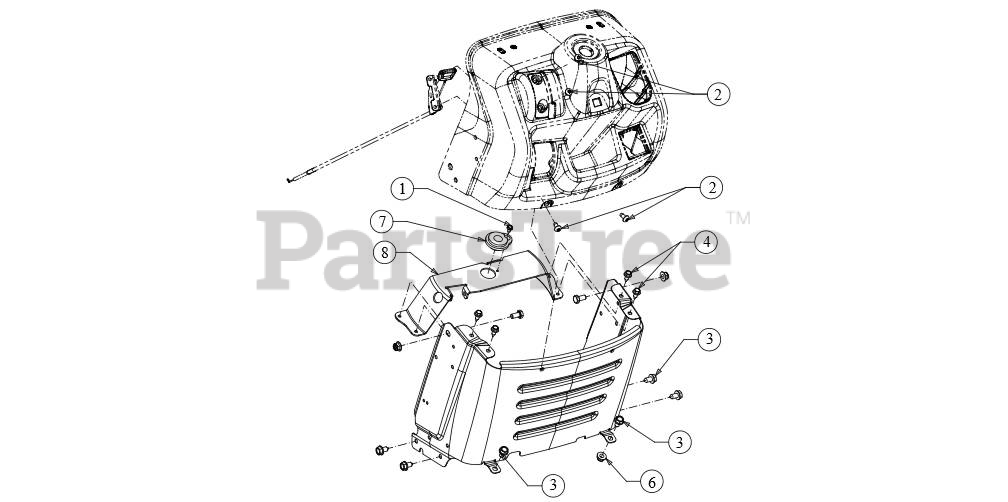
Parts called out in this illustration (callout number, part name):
1	HEX SCREW AB-TAP #10-16 X 0.500
2	SCREW 1/4-20 X .5
3	SCREW 5/16-18 X .625
4	SCREW 1/4-20X.625
6	FLANGE LOCK NUT 5/16-18
7	BEARING
